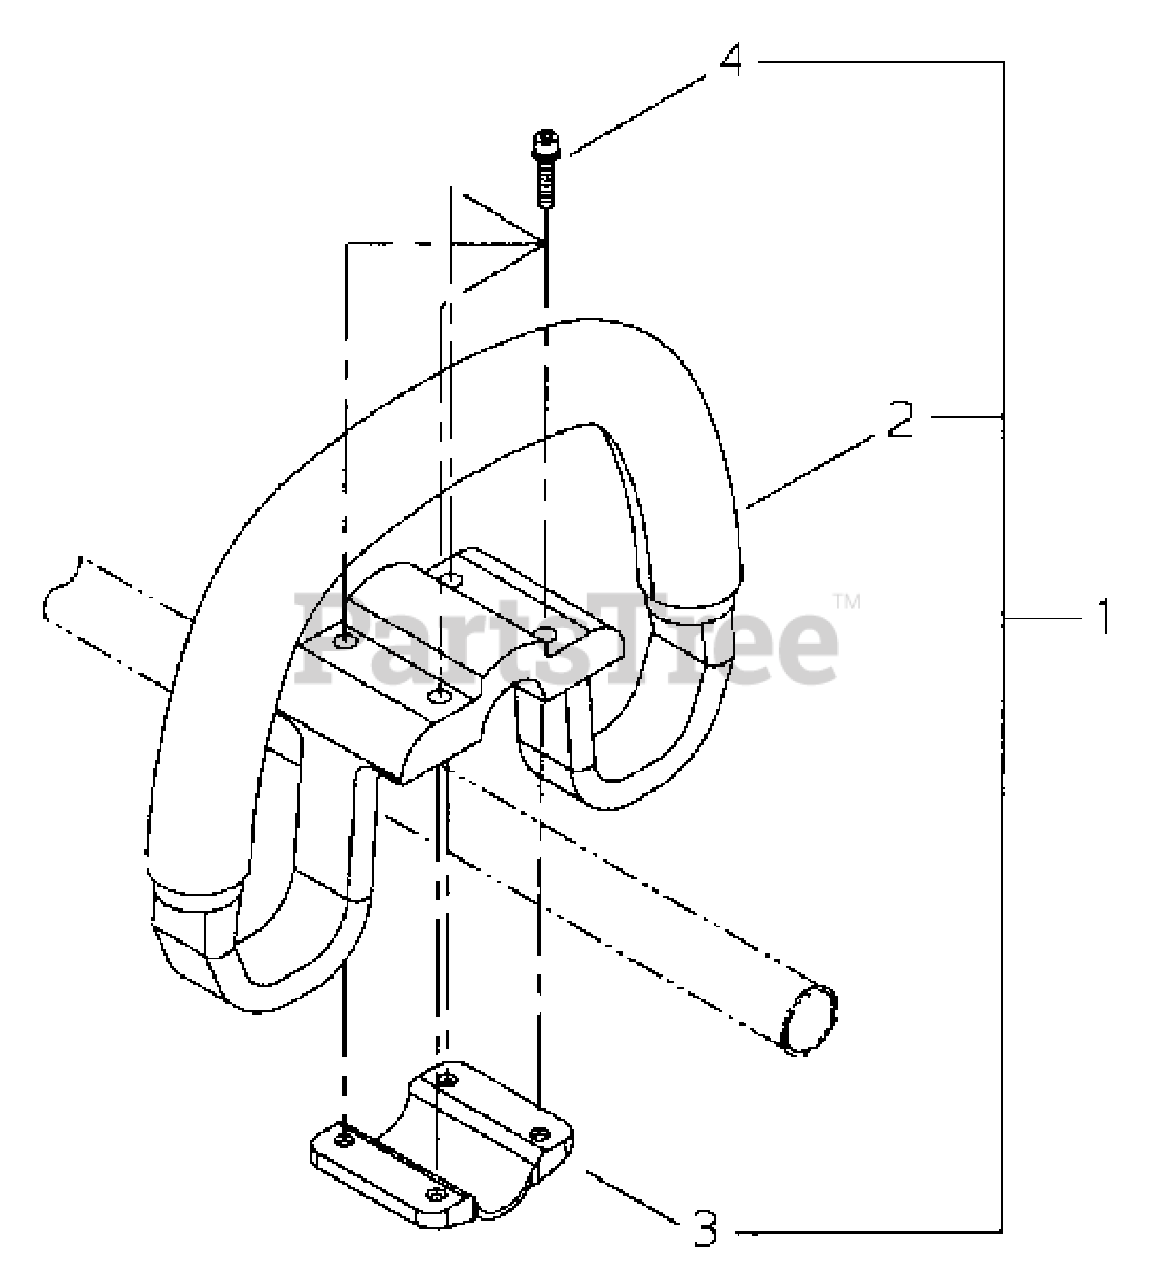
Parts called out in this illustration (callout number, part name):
1	HANDLE ASSY
2	HANDLE
3	CLAMP - LOWER
4	SCREW - 5X25
